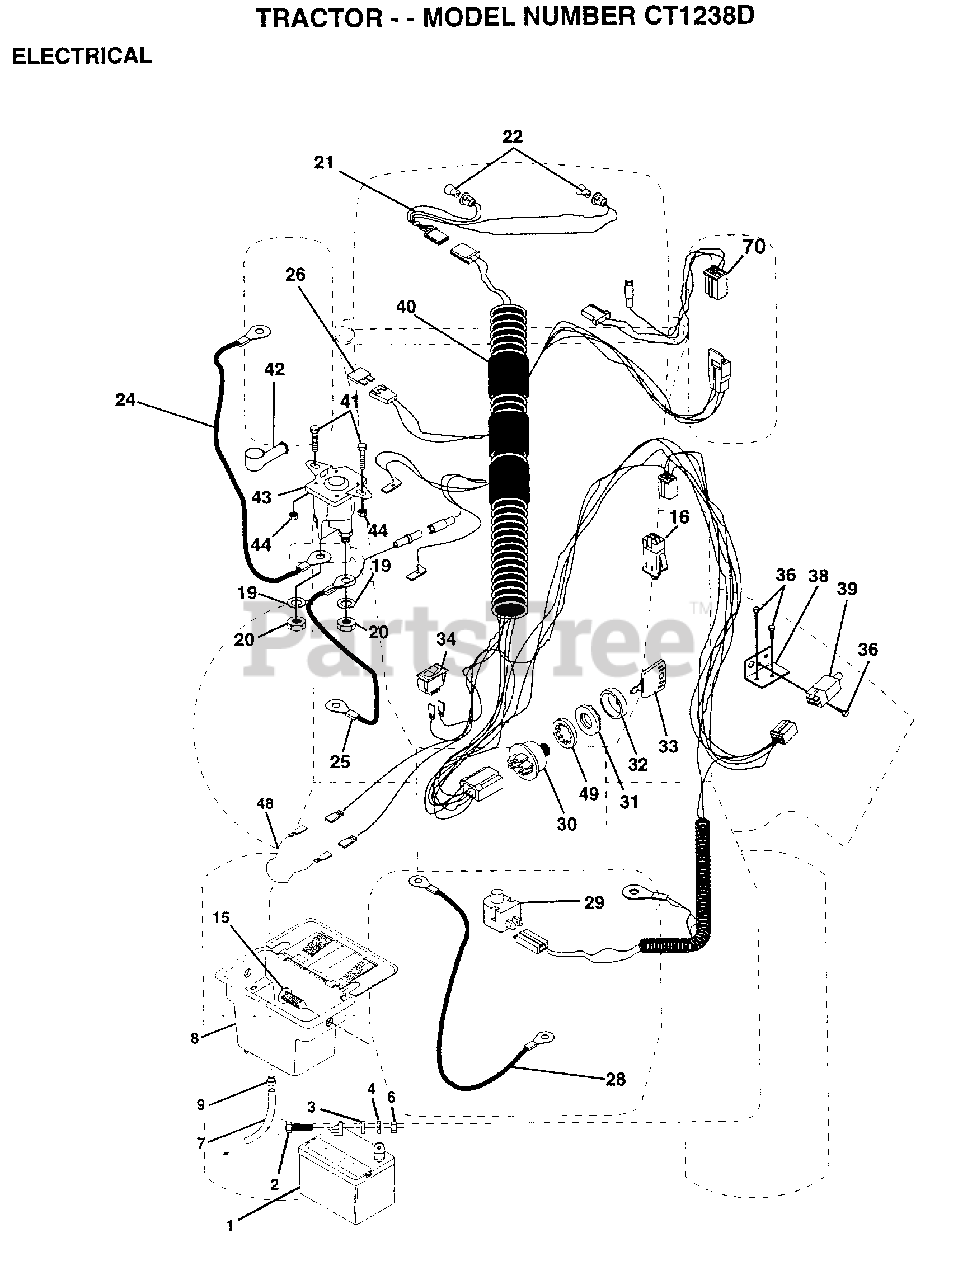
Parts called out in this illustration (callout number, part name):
2	BOLT LT
3	WASHER
4	LOCKWASHER
7	TUBE T
9	HOSE CLAMP T
15	FASTNER.SNAP-IN
16	SWITCH INTERLOCK
20	NUT
21	"HARNESS,LIGHT SOC"
22	HEADLAMP BULB
24	"CABLE T, BATTERY"
25	CABLE.BTRY.6GA.RD
26	FUSE HYT
28	CABLE T
29	SWITCH SEAT
32	COVER KEY SWITCH
33	KEY MLD GEN DELTA
34	SWITCH LT
36	SCREW
38	BRACKET SWITCH IN
39	SWITCH INTERLOCKT
40	HARNESS.IGN.DASH.
41	BOLT HXHD FIN
44	NUT HXKEP 1/4X20
48	ADAPTER AMMETER
49	WASHER PINNED
70	HARNESS ENG DUAL
